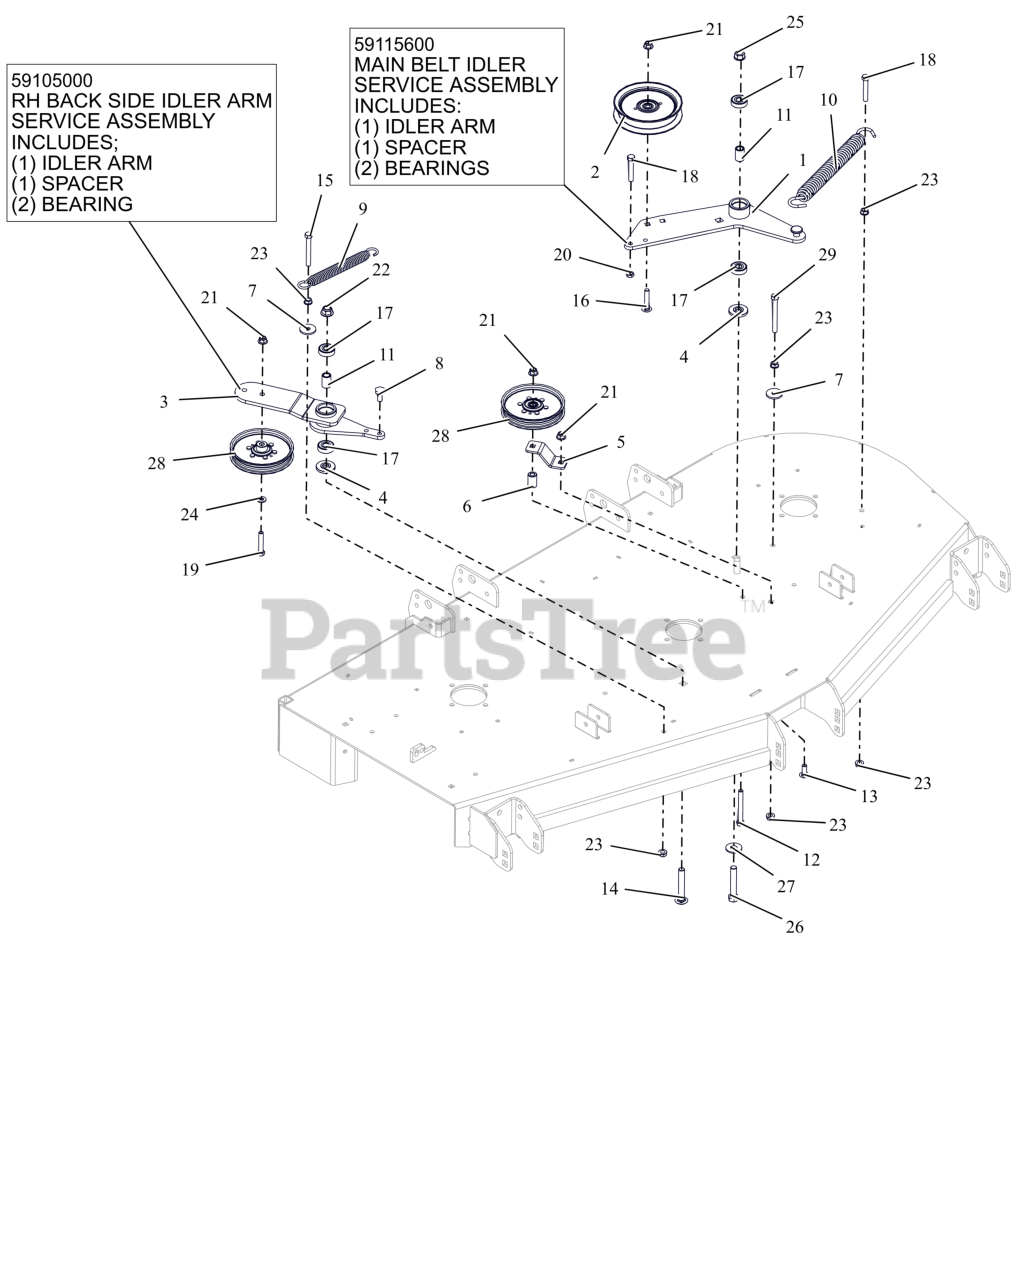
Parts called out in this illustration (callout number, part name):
1	WLDMT, DECK PTO IDLR ARM
1	ASSEMBLY, MAIN BELT IDLER
2	IDLER, FLAT 5.00"
3	WLDMT, DECK RH IDLER ARM
3	RH BACKSIDE IDLER ARM ASSEMBLY
4	SPACER, IDLER ARM
5	PTO FIXED IDLER MTG BRKT -RED
6	BUSHING, SLV .380X.750X1.190
7	WSHR,FLT .406X1.375X.135 ZCC
8	BLT,SHLDR EP .38-16X.30 HEX YZ
9	SPRING, EXTENSION
10	SPRING, EXTENSION
11	SPACER .510 X .75 X 1.1485
12	BLT, HEX .38-16X3.25 G5 ZCC
13	BLT,RHSSN .38-16X1.00 G5 ZCC
14	BTL,RHSSN .500-13 X 3.25 G5 ZCC
15	BLT, HEX .38-16X3.00 G5 ZCC
16	BLT,RHSSN.375-16X2.00 G5 ZCC
17	BRG-BALL .500X1.38X.437
18	BLT,HEX .38-16X2.25 G5 ZCC
19	BLT,HEX .38-16X2.00 G5 ZCC
20	NUT-JAM .375-16 G2 ZCC
21	NUT,NYL-FLG .38-16 GF ZCC
22	NUT,NYL-FLG .50-13 GF ZCC
23	NUT, SPNLK-FLG .38-16 G5 ZCC
24	WSHR,FLT .406X.812X.065 ZCC
25	NUT-LK-CTR-FLG .500-13 GG ZCC
26	BLT, HEX .50-13X3.00 G5 ZCC
27	WSHR,FLT .563X1.375X.109 ZCC
28	PULLEY, FLAT IDLER
29	BLT, HEX .38-16X3.50 G5 ZCC
